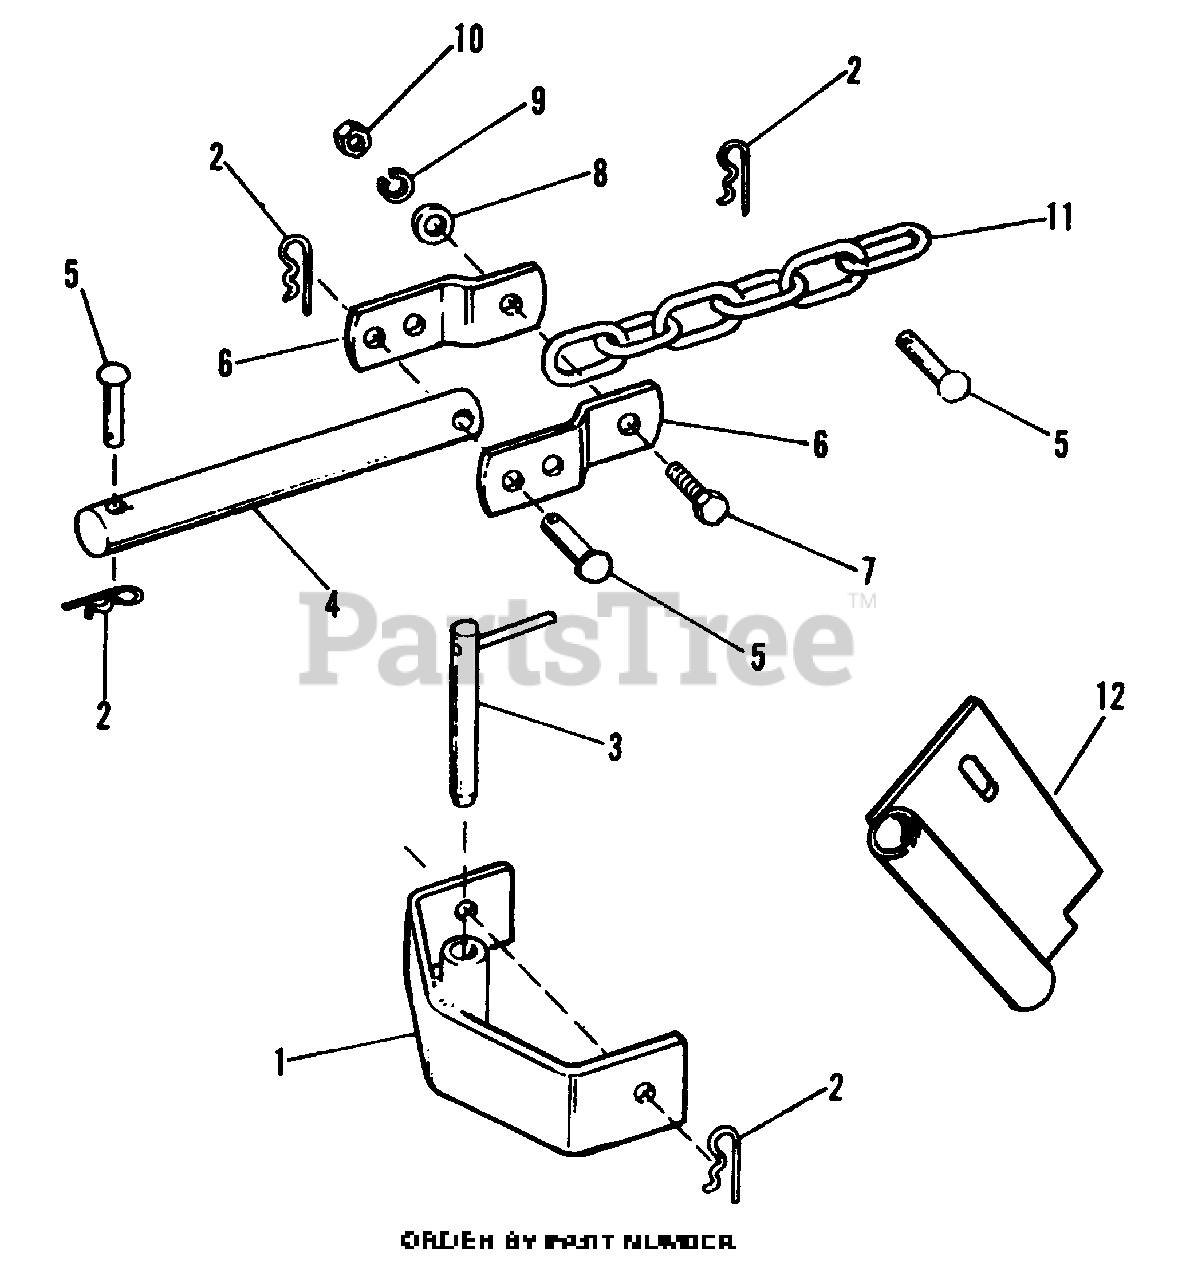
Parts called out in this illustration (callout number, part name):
1	Clevis Assembly
2	Spring Clip
3	Hitch Pin Assembly
4	Plow Lift Pin
5	Pin
7	Hex Capscrew, 3/8"-16 x 1-1/2" lg.
8	Plain Washer, 3/8"
9	Lockwasher, 3/8"
10	Hex Nut, 3/8"-16
11	Plow Lift Chain
12	Support Assembly
